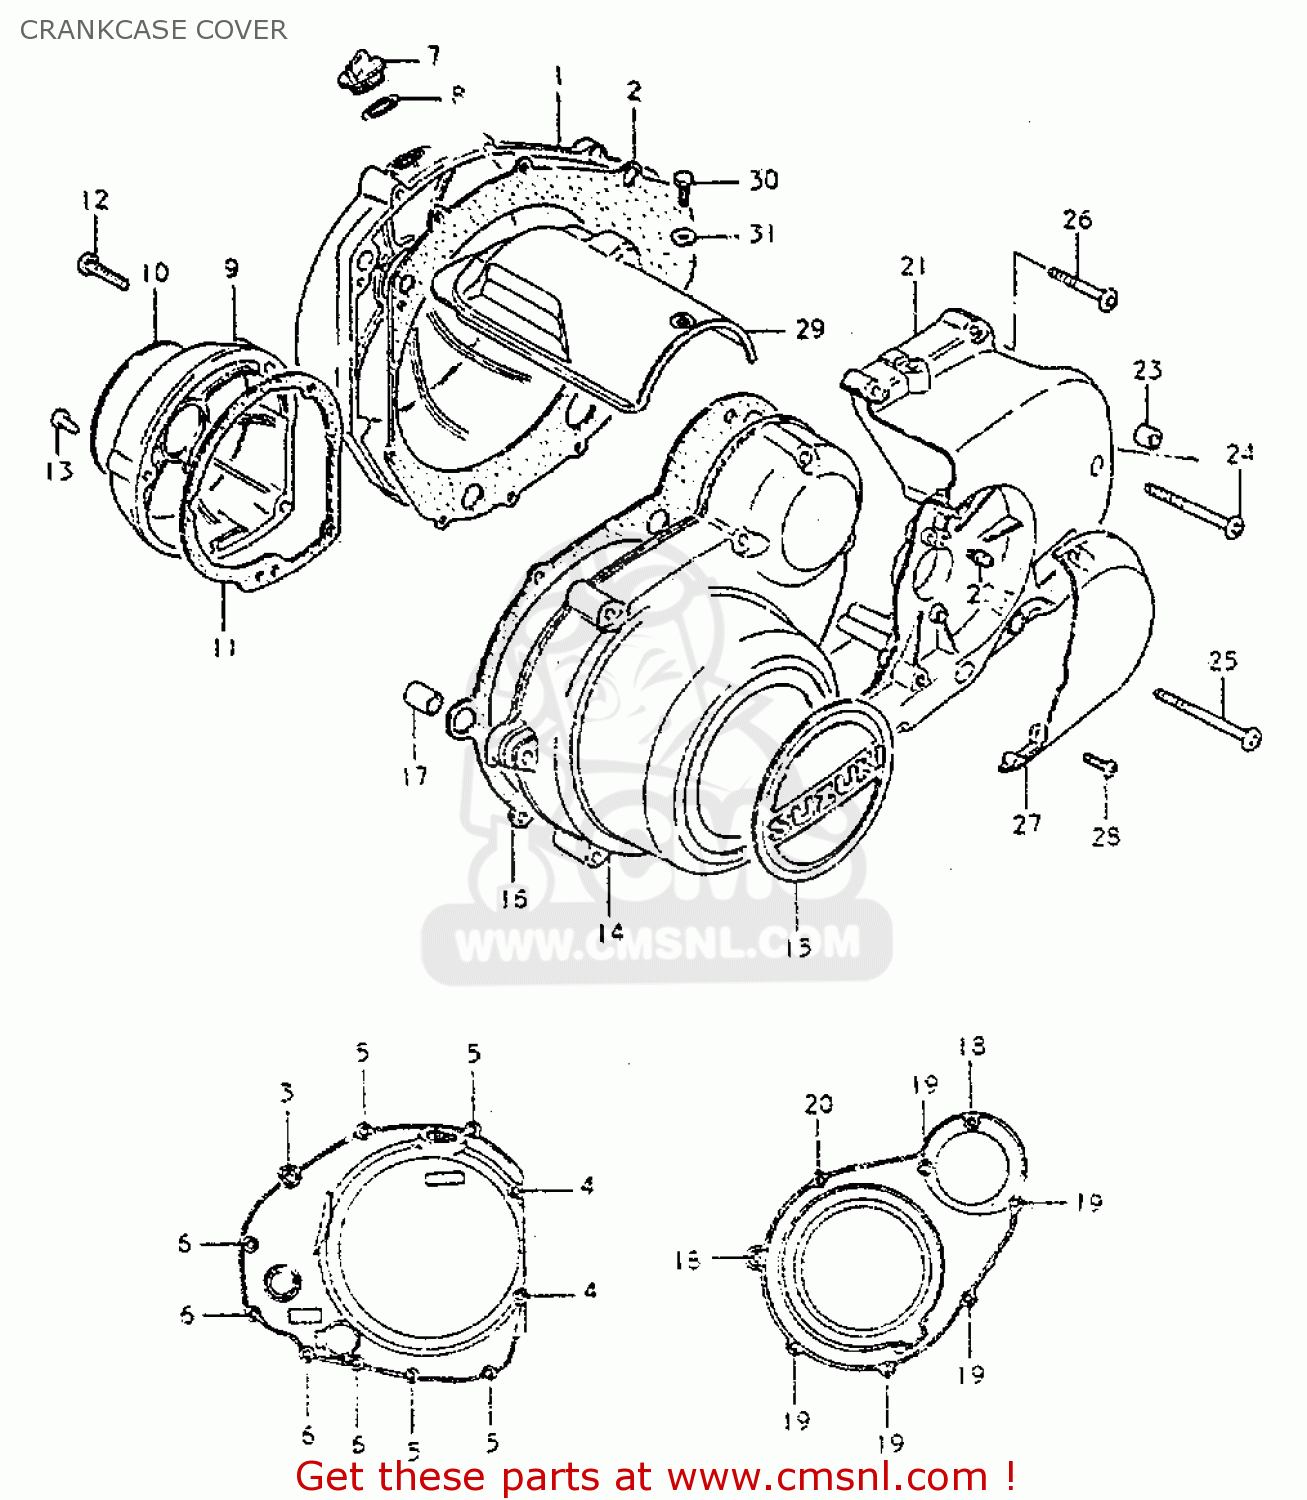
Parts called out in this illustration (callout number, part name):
1	COVER,CLUTCH
2	GASKET,CLUTCH COVER (MCA)
3	SCREW (6X35)
4	SCREW
5	SCREW
6	SCREW
7	CAP
8	O RING(D:2.2,ID:32)
9	COVER,CONTACT BREAKER
10	EMBLEM,CONTACT BREAKER COVER
11	GASKET,CONTACT BREAKER COVER (NAS)
12	SCREW
13	SCREW
14	COVER
15	EMBLEM,MAGNETO COVER
16	GASKET,MAGNETO COVER (MCA)
17	PIN
18	SCREW (6X45)
19	SCREW
20	SCREW (6X35)
21	CRANKCASE SET
22	NIPPLE
23	PIN
24	SCREW
25	SCREW 6X80
26	SCREW 6X30
27	CAP,CLUTCH RELEASE ADJUST
28	SCREW
29	COVER,STARTER MOTOR
30	BOLT
31	WASHER
